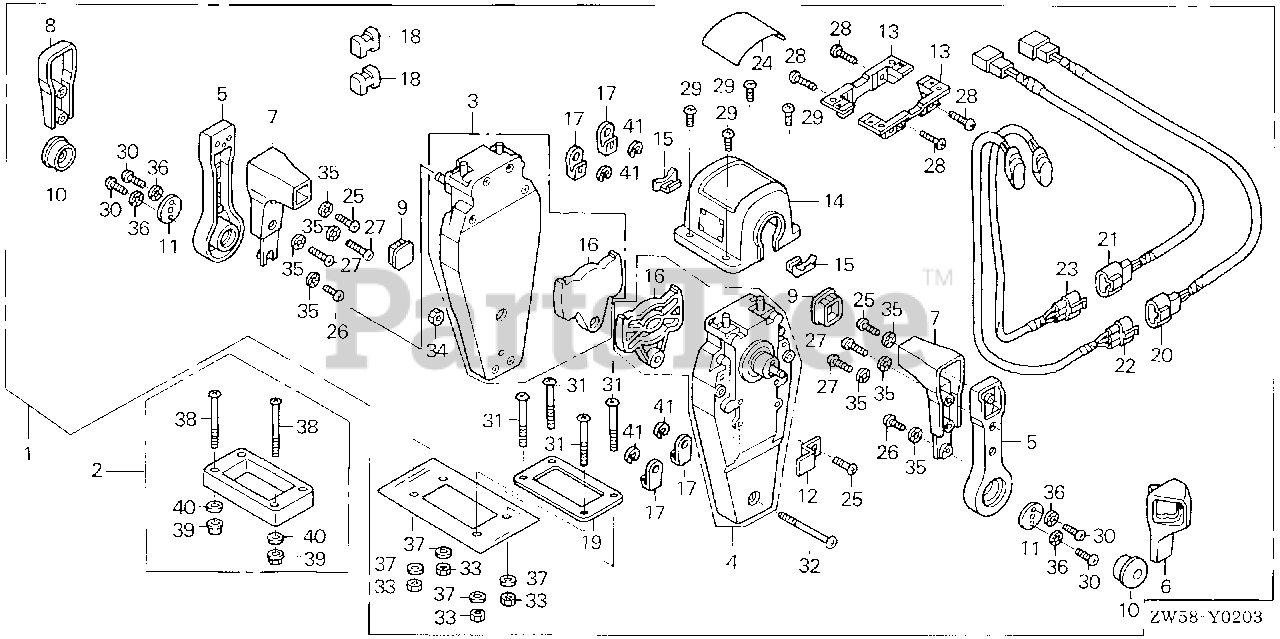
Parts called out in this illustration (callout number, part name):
1	BOX KIT, REMOTE CONTROL (TOP MOUNT DUAL)(L)
2	SPACER KIT, REMOTE CONTROL BOX (TOP MOUNT DUAL)
3	HOUSING ASSY., L. (INNER) (TOP MOUNT)
4	HOUSING ASSY., R. (INNER) (TOP MOUNT)
5	HANDLE, REMOTE CONTROL
6	COVER, R. GRIP
7	GRIP, REMOTE CONTROL HANDLE
8	COVER, DUAL GRIP
9	CAP, GRIP
10	BUTTON, THROTTLE
11	PLATE, HANDLE
12	PLATE, CABLE CLAMP
13	BRACKET, REMOTE CONTROL HOUSING
14	HOUSING, DUAL REMOTE CONTROL BOX
15	HOUSING, LEAD
16	PLATE, DWELL
17	TERMINAL, CABLE
18	SPACER, CABLE CLAMP
19	GASKET, DUAL
20	SUB-HARNESS ASSY., POWER TRIM-TILT (A)
21	SUB-HARNESS ASSY., POWER TRIM-TILT (B)
22	SWITCH ASSY., POWER TRIM-TILT (A)
23	SWITCH ASSY., POWER TRIM-TILT (B)
24	MARK, REMOTE CONTROL (DUAL)
25	SCREW, PAN (5X16)
26	SCREW, PAN (5X10)
27	SCREW, PAN (5X20)
28	SCREW, PAN (5X18)
29	SCREW, PAN (4X10)
30	SCREW, PAN (6X18)
31	SCREW, PAN (5X40)
32	SCREW, PAN (5X55)
33	NUT, HEX. (5MM)
34	NUT, HEX. (5MM)
35	WASHER, LOCK (5MM)
36	WASHER, LOCK (6MM)
37	WASHER, PLAIN (5MM)
38	SCREW, PAN (5X65)
39	NUT, HEX. (5MM)
40	WASHER, PLAIN (5MM)
41	E-RING (6MM)
